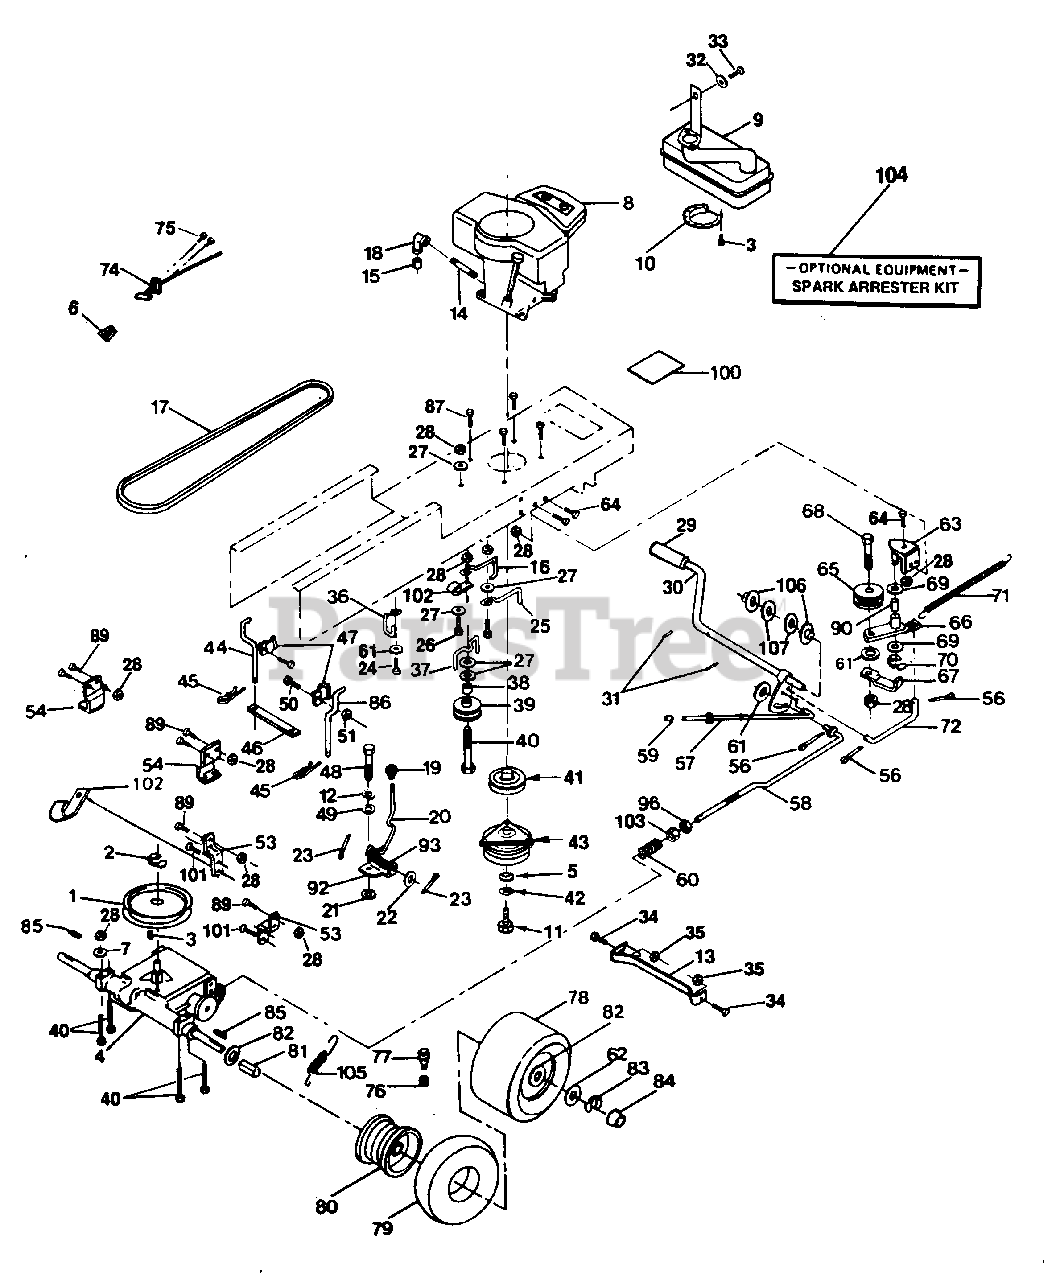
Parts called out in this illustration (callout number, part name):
1	Transaxle (Driven) Pulley (AYP part number)
2	Retainer Ring (AYP part number)
3	Spider Lock Screw (AYP part number)
4	Foote Dana 6-speed Transaxle, Model No. 4360-19 (AYP part number)
5	Washer (AYP part number)
6	Throttle Control Knob (AYP part number)
7	Washer (AYP part number)
8	14HP Kohler Command Engine
9	Muffler (AYP part number)
10	Muffler Deflector (AYP part number)
11	Hex Bolt (AYP part number)
12	Lock Washer 1/4 (AYP part number)
13	Clutch Retainer (AYP part number)
14	Pipe Nipple (AYP part number)
15	Pipe Coupling (AYP part number)
17	Drive V-Belt (AYP part number)
18	Elbow (AYP part number)
19	Knob (AYP part number)
20	Shifter Rod (AYP part number)
21	Shift Plate Washer (AYP part number)
22	Washer (AYP part number)
23	Cotter Pin 1/8 x 1 (AYP part number)
24	Thread Roll Washer Hex Screw (AYP part number)
25	Engine Belt Keeper (AYP part number)
26	Hex Bolt 3/8-16 x 1 (AYP part number)
27	Washer (AYP part number)
28	Locknut
29	Pedal Cover (AYP part number)
30	Foot Pedal Shaft (AYP part number)
31	Roll Pin (AYP part number)
32	Lock Washer (AYP part number)
33	Hex Bolt (AYP part number)
34	Carriage Bolt
35	Locknut
36	Belt Retainer (AYP part number)
37	Belt Keeper (AYP part number)
38	Spacer (AYP part number)
39	Flat Idler (AYP part number)
40	Hex Bolt 3/8-16 x 2-3/4 (AYP part number)
41	Engine Pulley (AYP part number)
42	Lock Washer 7/16 (AYP part number)
43	Electric Clutch (AYP part number)
44	L.H. Belt Keeper (AYP part number)
45	Spring Retainer (AYP part number)
46	Locator Strap (AYP part number)
47	Clamp (AYP part number)
48	Hex Bolt 1/4-28 x 3/4 (AYP part number)
49	Washer (AYP part number)
50	Hex Bolt 5/16-18 x 3/4 (AYP part number)
51	Locknut
53	Torque Strap (AYP part number)
54	Transaxle Bracket (AYP part number)
56	Cotter Pin (AYP part number)
57	Park Brake Rod (AYP part number)
58	Brake Rod (AYP part number)
59	Cap (AYP part number)
60	Brake Rod Spring (AYP part number)
61	Washer 13/32 x 13/16 x 16 Ga. (AYP part number)
62	Washer (AYP part number)
63	Clutch Bracket (AYP part number)
64	Carriage Bolt (AYP part number)
65	Idler Pulley (AYP part number)
66	Idler Arm (AYP part number)
67	Belt Retainer (AYP part number)
68	Hex Bolt 3/8-16 x 1-1/2 (AYP part number)
69	Hardened Washer (AYP part number)
70	Klip Ring (AYP part number)
71	Clutch Return Spring (AYP part number)
72	Clutch Link (AYP part number)
74	Throttle Control (AYP part number)
75	Thread Cutting Hex Screw (AYP part number)
76	Valve Cap (AYP part number)
77	Valve Stem (AYP part number)
78	Rear Tire (AYP part number)
79	Tube (Not furnished with Tractor) (AYP part number)
80	Rim (AYP part number)
81	Split Spacer (AYP part number)
82	Washer (AYP part number)
83	E-Ring (AYP part number)
84	Rear Hub Cap (AYP part number)
85	Square Key (AYP part number)
86	R.H. Belt Keeper (AYP part number)
89	Hex Bolt 3/8-16 x 3/4 (AYP part number)
90	Bearing (AYP part number)
92	Shifter Plate Assembly (AYP part number)
93	Torsion Spring (AYP part number)
96	Hex Jam Nut 3/8-16 (AYP part number)
98	Washer (AYP part number)
100	Decal (AYP part number)
101	Thread Roll Washer Hex Screw
102	Fuel Line Clip (AYP part number)
103	Locknut (AYP part number)
104	Spark Arrestor Kit (AYP part number)
105	Return Brake Spring (AYP part number)
106	Nylon Bearing (AYP part number)
107	Washer (AYP part number)
